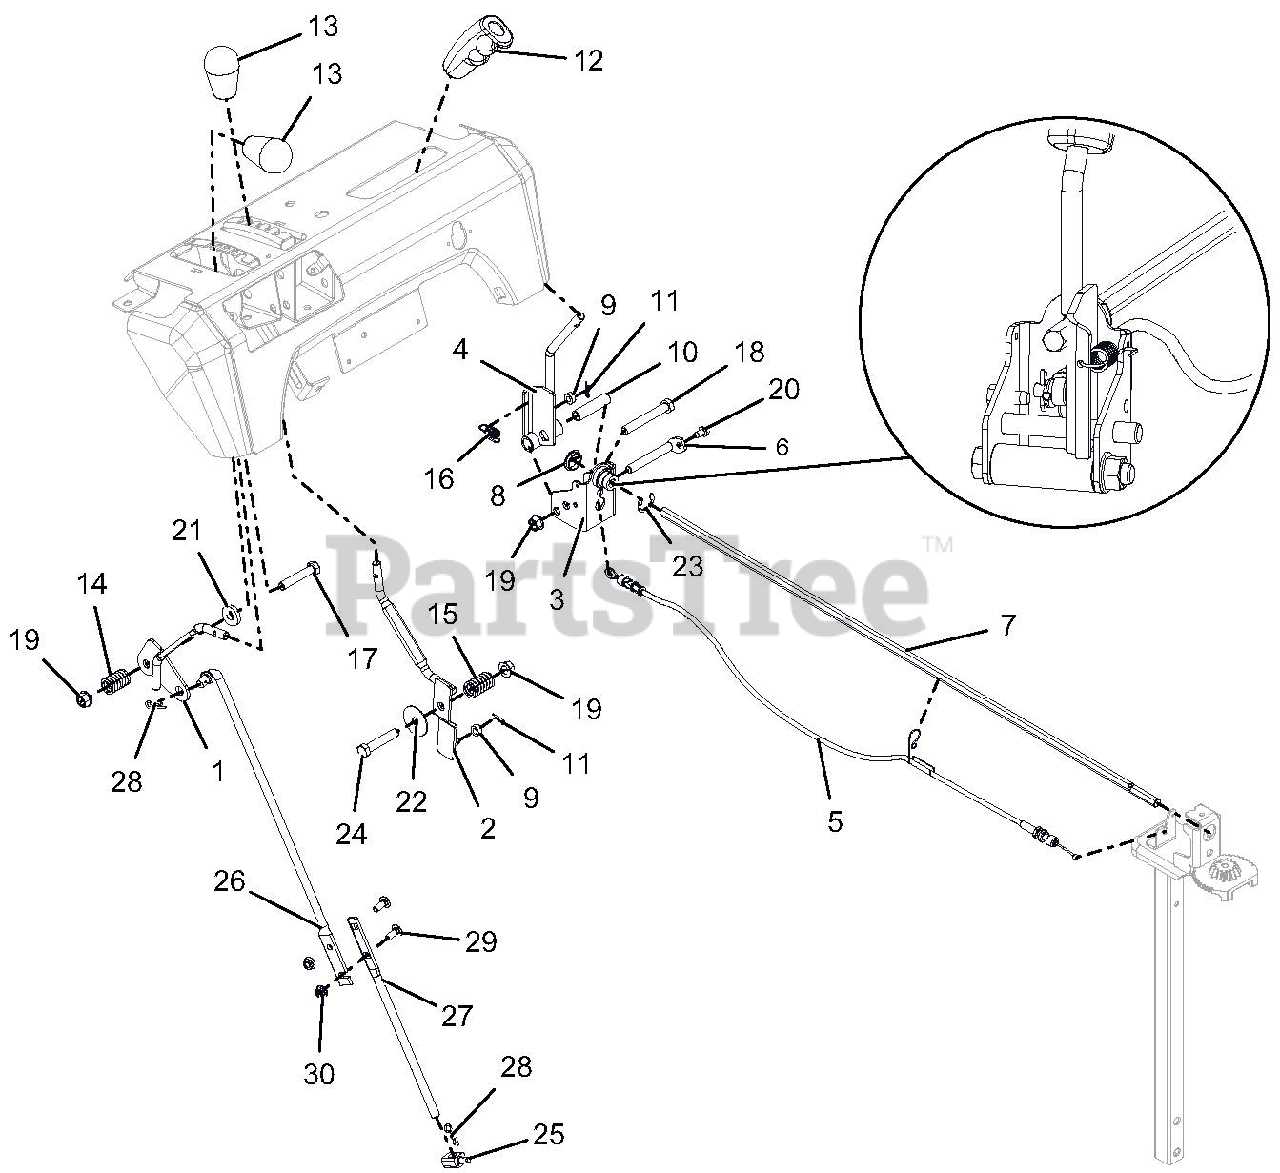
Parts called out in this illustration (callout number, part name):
1	WELDMENT, CONTROL LEVER(SHIFT)
2	WELDMENT, CONTROL LEVER (DEFL)
3	WELDMENT-CONTROL BRACKET-CHUTE
4	WELDMENT, CONTROL LEVER
5	CABLE, CHUTE LOCK, PRO
6	ROD, PIVOT - INTERLOCK
7	ROD, HEX - CHUTE ROTATION
8	BUSHING, POLYLINER-.75 SNAPIN
9	BSHG-SLV .265X.500X.219
10	SPCR, WHEEL .385X.500X2.00
11	PIN-HAIR INT .06X.18X.77
12	CONTROL HANDLE, QUICK TURN
13	KNOB,SOFT TEARDROP,PUSH-ON GRY
14	SG-COMP .125X.781X1.250
15	SG-COMP .125X.781X1.250
16	SPRING-EXT .047X.438X1.45
17	@BLT-HEX .31-18X2.25 GR5 YWZC
18	@BLT-HEX .38-16X2.75 GR5 YWZC
19	@NUT-LK-TOP-FLG .38-16 YWZC
20	SCR-TAP .25-20X.50 HWH TR YWZ
21	WSHR-FL-STL .630X1.005X.062 YZ
22	WSHR-FL-STL .380X1.50X.062 YWZ
23	E-RING .750X.050
24	@BLT-HEX .38-16X2.00 GR5 YWZC
25	PIVOT,SHIFT ROD .375-16(TRUNN)
26	ROD, SHIFT - UPPER
27	ROD, SHIFT - LOWER
28	PIN-HAIR INT .08X.18X1.18 YWZC
29	@BLT-RDHDSQNK .25-20X.75 G5YZ
30	@NUT-LK-CTR-FLG .25-20 YWZC
